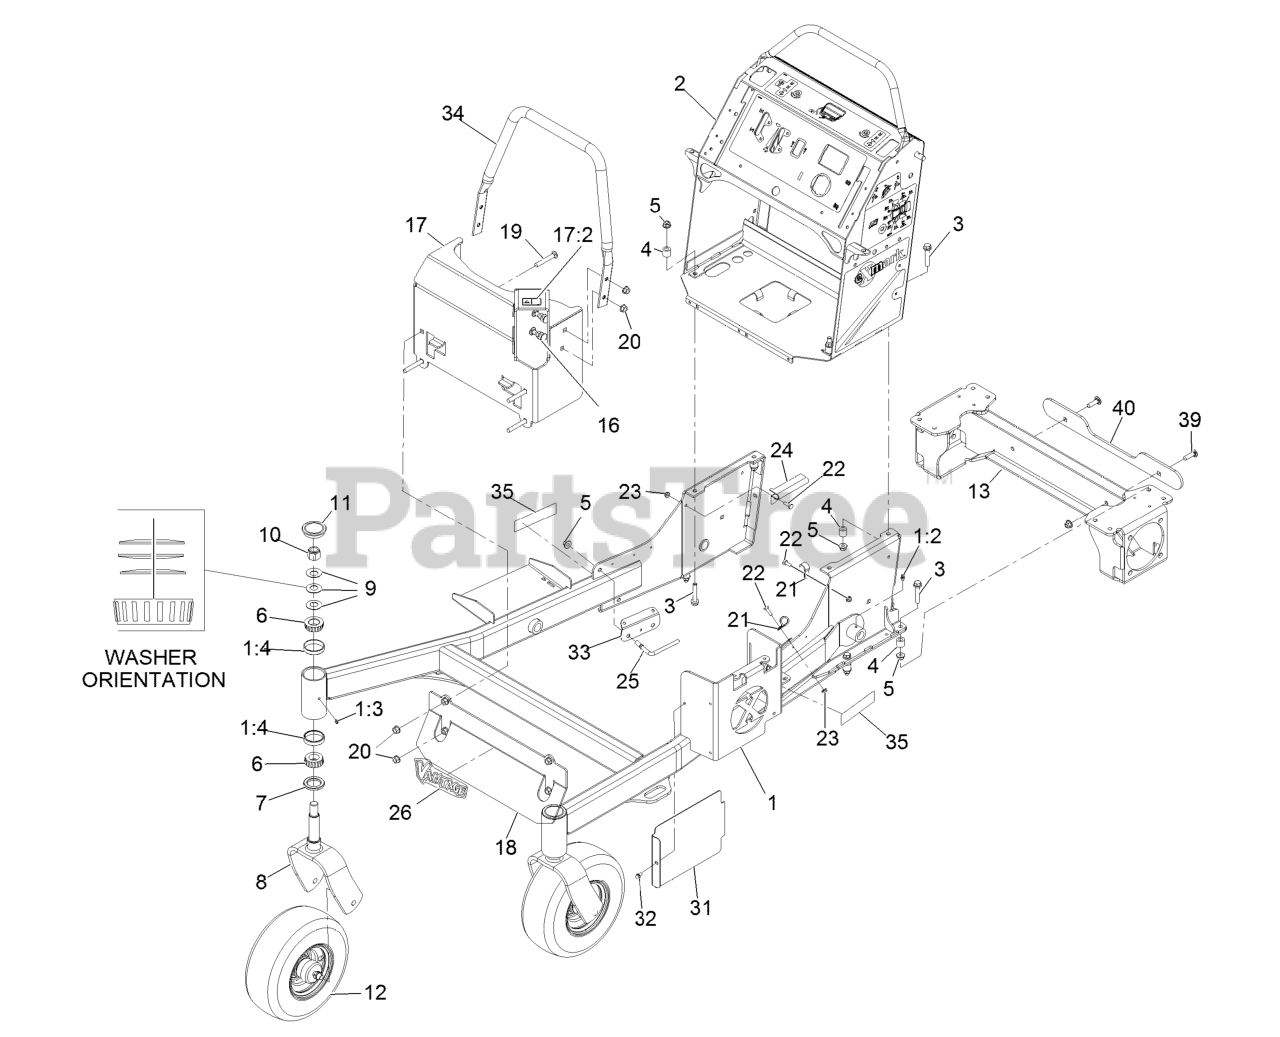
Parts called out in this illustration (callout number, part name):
1	FRONT FRAME ASM
1:2	FITTING-GREASE
1:4	CUP-BEARING
2	CONTROL TOWER ASM-EFI
3	SCREW-HHF
5	NUT-HF, NI
6	Cone-Bearing Tapered Roller
7	SEAL-GREASE
8	FORK-CASTER
9	WASHER-BELLVILLE
10	NUT-LOCK, NI
11	CAP-GREASE
12	WHEEL/TIRE AND BEARING AS
13	WELD, MOTOR FRAME
16	SCREW-CARR
17:2	DECAL-WARNING
18	PANEL-GUARD
19	SCREW-CARR
21	CLAMP-CABLE
22	SCREW-HH
24	BRACKET-HOSE, FUEL
25	GUIDE-HOSE, SUPPORT
26	DECAL-VANTAGE LOGO
31	SHIELD-HEAT, TALL
32	SCREW-HWH
33	GUARD-HOSE
34	TUBE-GUARD
35	DECAL-S-SERIES
39	SCREW-CARR
40	PLATE, BUMPER SPACER
